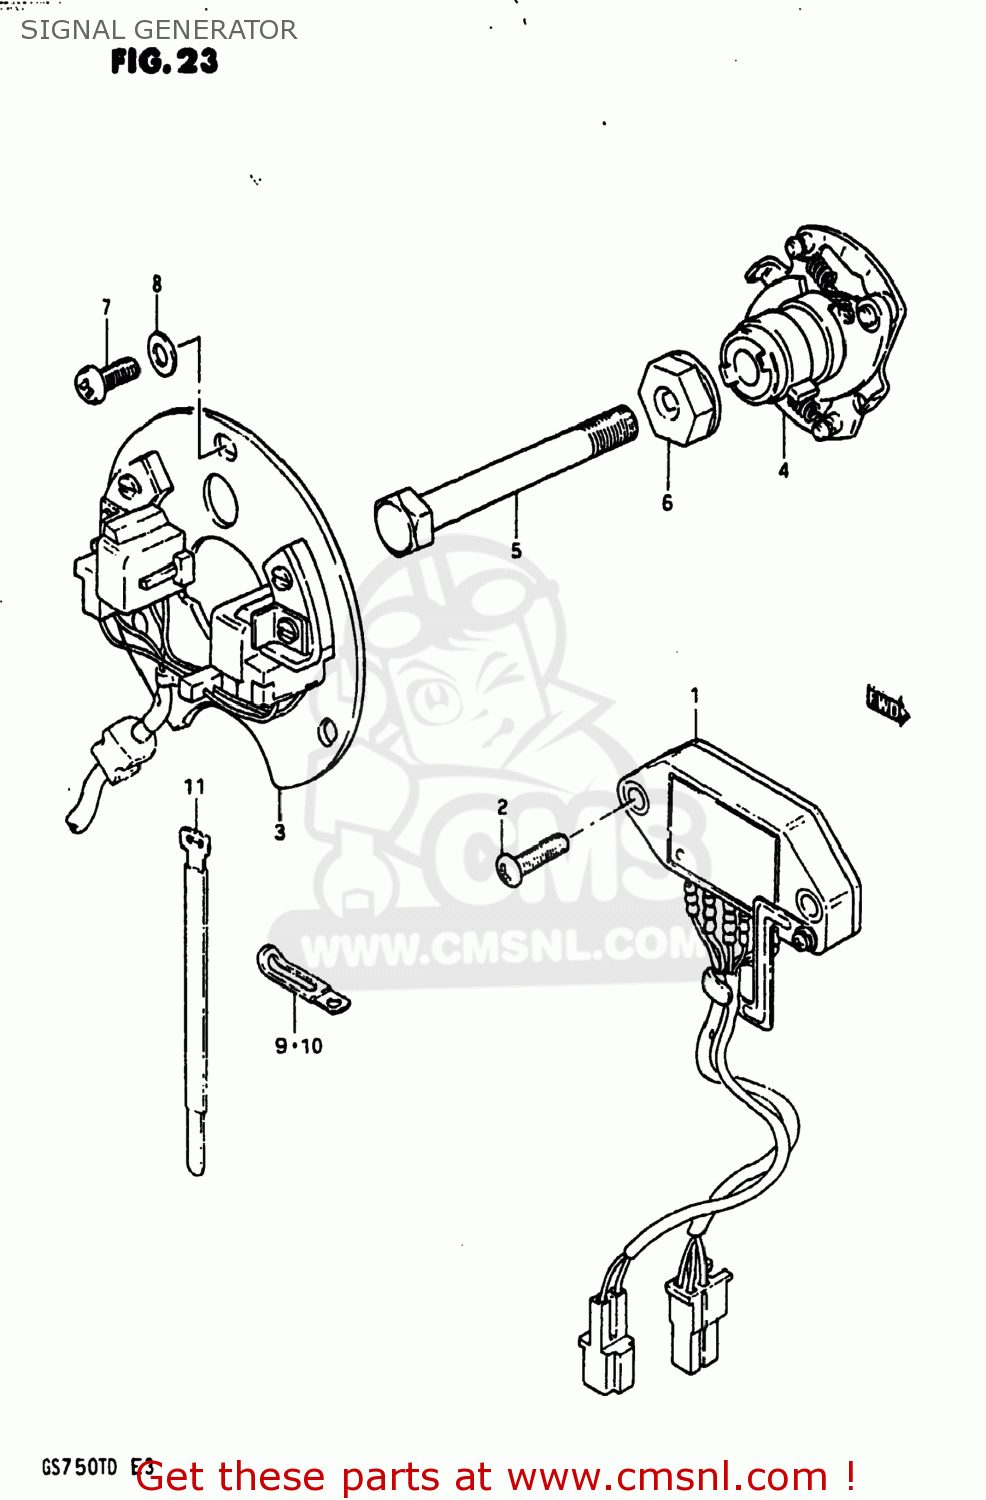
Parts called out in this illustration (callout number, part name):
1	IGNITER UNIT
2	SCREW
3	SIGNAL GENERATOR ASSEMBLY
4	GOVERNOR ASSEMBLY
5	BOLT
6	WASHER
7	SCREW(5X12)
8	WASHER
9	CLAMP L:35
10	CLAMP
11	CLAMP
